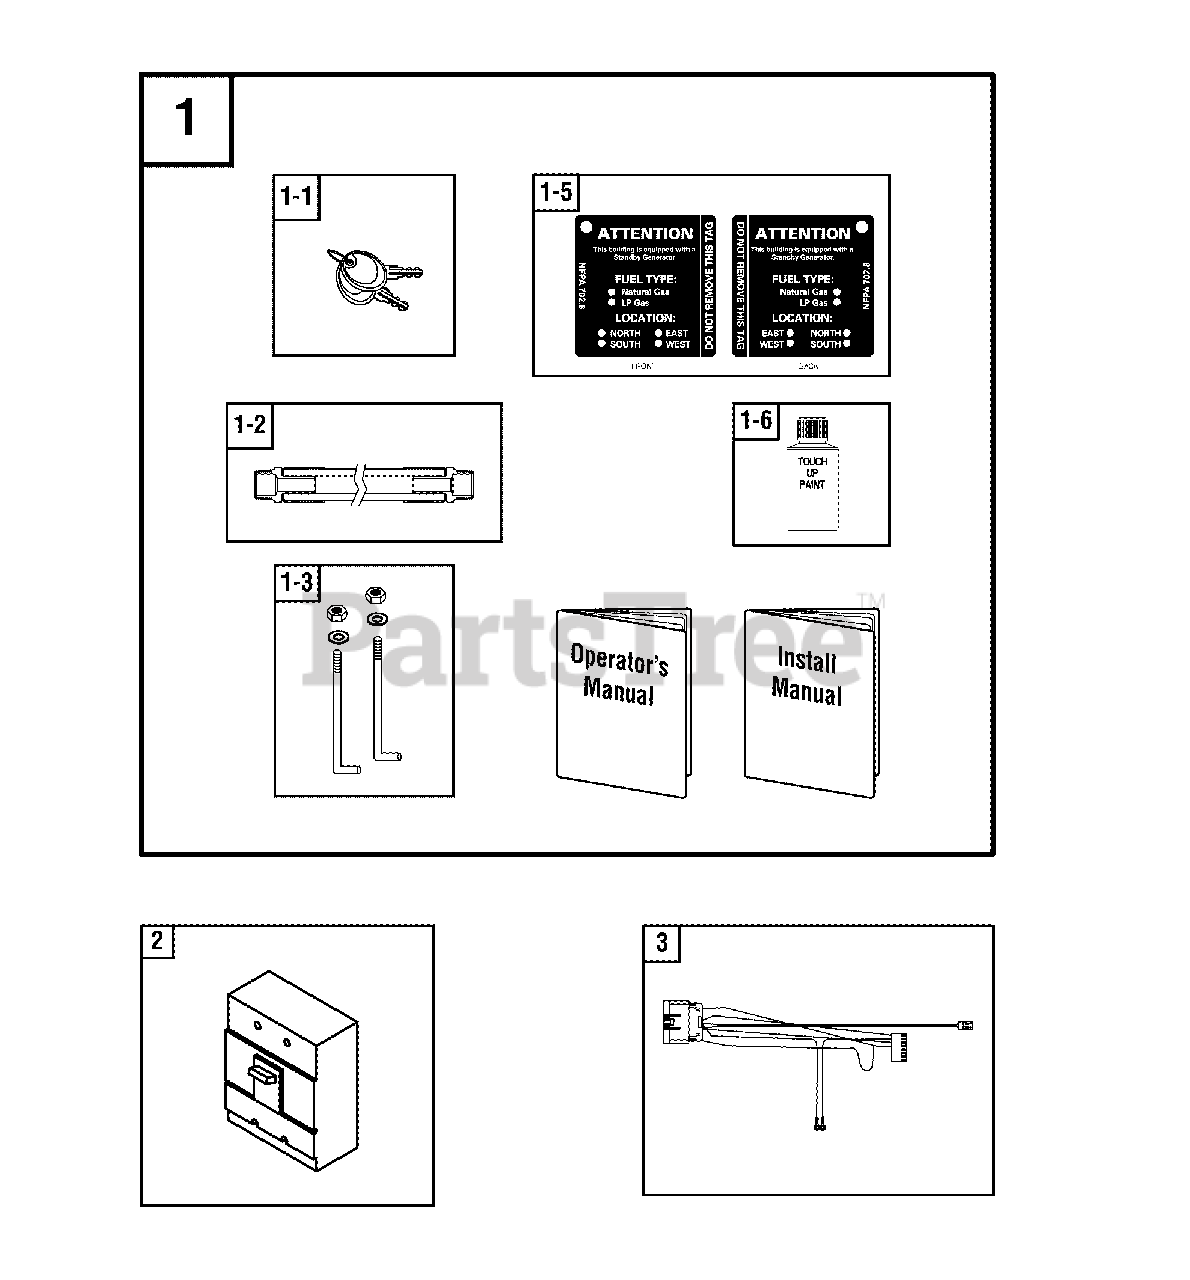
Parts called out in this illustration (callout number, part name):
1	KIT-MANUAL, ACC
1-3	KIT-HOLD DOWN, BATTERY
1-5	DECAL-ATTN STANDBY EQUIPMENT
1-6	PAINT-TOUCH-UP, ALMOND TEXTURE
2	BREAKER-CIRCUIT
